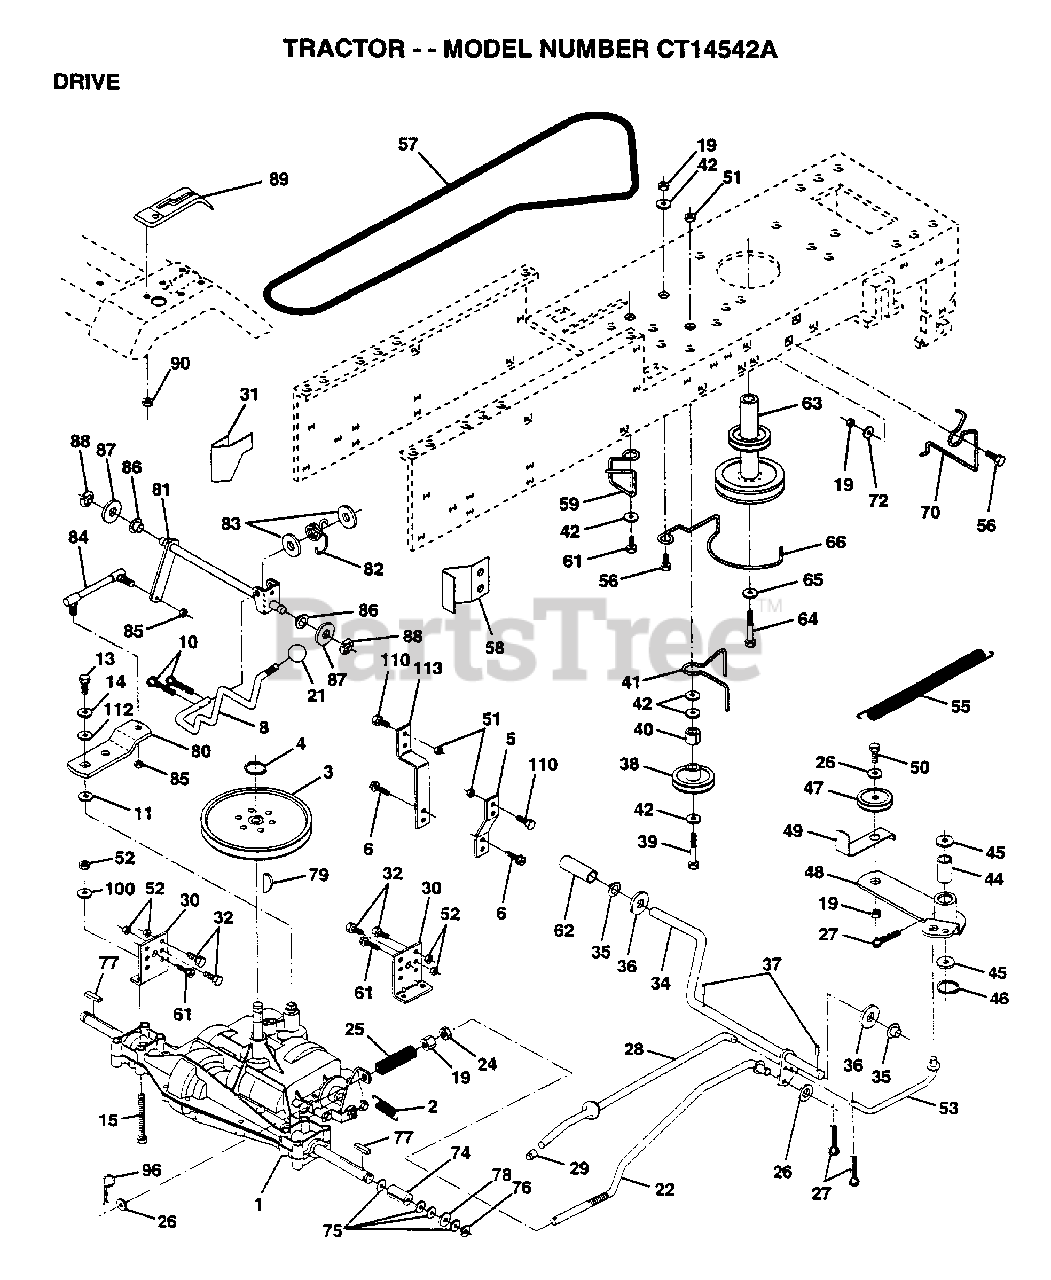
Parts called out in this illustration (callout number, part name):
2	SPRING.BRAKE.RETU
3	PULLEY TRANS
5	STRAP TORQUE
6	SCREW
8	ROD SHIFT FEND LT
10	PIN COTTER 1/8
11	WASH-SHFT PLT LT
12	BOLT.1/4-28.W/PAT
13	BOLT.1/4-28.W/PAT
14	LOCKWASHER
15	BOLT HEX
18	BOLT
19	NUT
21	CONTROL KNOB LT
22	BRAKE ROD
24	NUT
25	SPRING ROD LT
26	WASHER
27	COTTER PIN
28	ROD.BRAKE.PARK.LT
30	TRANSAXLE MTG BKT
31	"KEEPER,BELT LH T"
32	BOLT
35	NYLON BEARING
36	WASHER LT
38	PULLEY.IDLER.FLAT
39	BOLT
40	SPACER T
41	BELT KEEPER LT
42	WASHER
44	"LY, BEARING"
45	WASHER LT
46	KLIP RING
48	ARM IDLER
49	RETAIN BELT
53	"LINK, CLUTCH T"
55	"SPRING, RETURN LT"
58	"KEEPER,BELT RH T"
59	KEEPER BELT CNTSP
61	SCREW
62	PEDAL COVER T
63	PULLEY.ENGINE
64	BOLT
65	LOCKWASHER
66	KEEPER.BELT.ENG.L
70	KEEPER BELT ENG
72	WASHER
74	SPACER AXLE
75	WASHER
76	E-RING LT
77	SQUARE KEY
78	WASHER
80	"ARM.SHIFT.20""TIRE"
82	"SPRING,TORSION"
83	WASHER
84	"ROD.TIE.20""P930LT"
85	NUT 1/4-28
86	BUSHING
87	WASHER D
88	KLIP RING
90	NUT
96	RETAINER M
100	WASHER M
112	WASHER LT
113	"STRAP,TORQUE"
